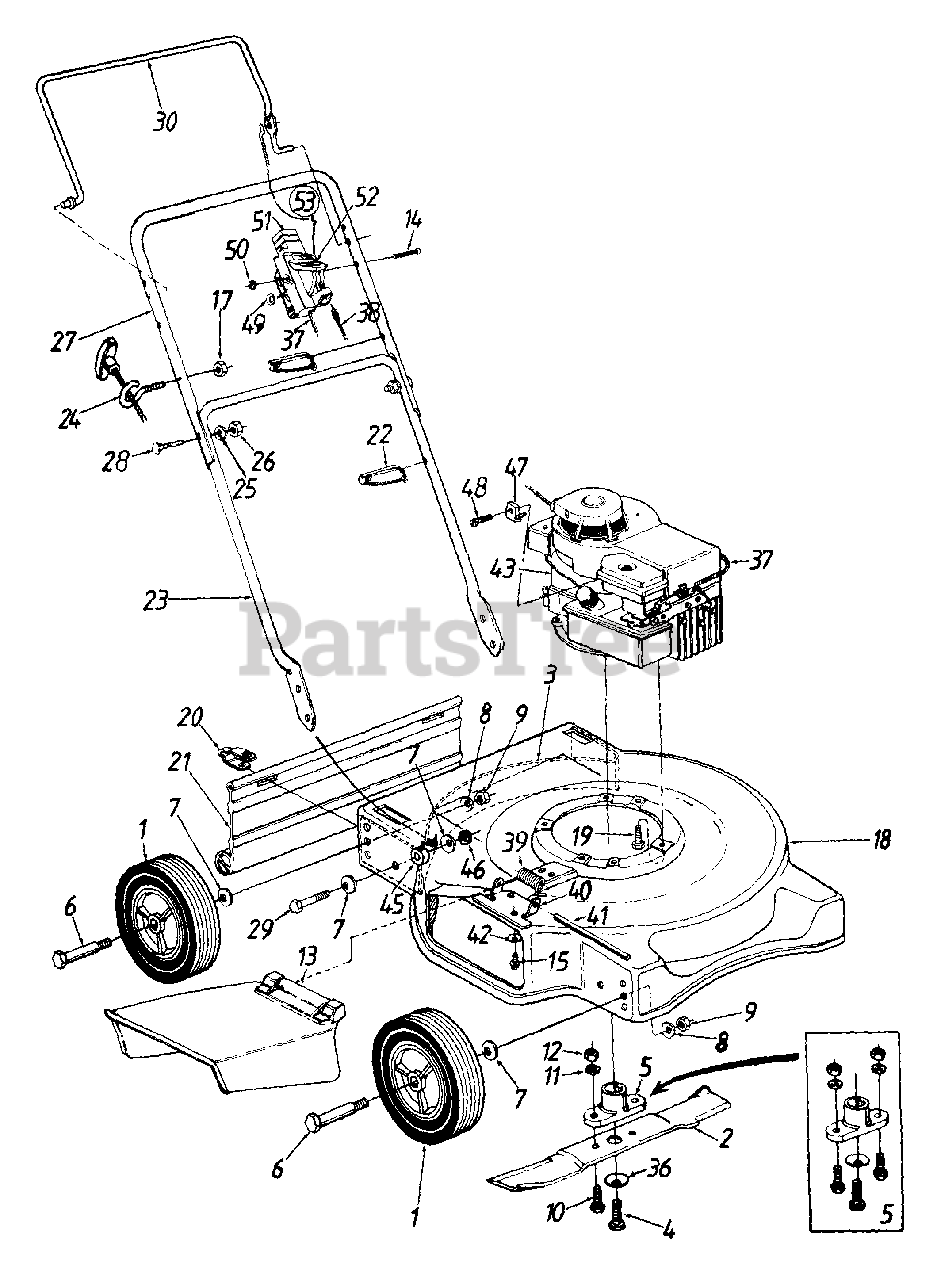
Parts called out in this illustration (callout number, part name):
1	Wheel Ass'y. Complete
2	20" Blade
5	Blade Adapter Kit (Keyed)
6	Axle Bolt
7	Bell-Wash..380" I.D. x .88"
8	Bell-Wash..39" I.D. x 1.13"
9	Hex Nut 3/8-16 Thd.
10	Hex Bolt 3/8-24 x 1" Lg.
11	L-Wash. 3/8" I.D.
12	Hex Nut 3/8-24 Thd.
13	Chute Deflector Ass'y.
14	Oval C-Sunk Scr.
15	Self-Tap Scr. 1/4-20 x .5" Lg.
17	Hex L-Nut 1/4-20 Thd.
20	Hinge Clip
21	Rear Flap 16.69" Lg.
22	Cable Tie
24	Rope Guide
25	L-Wash. 5/16" I.D.
26	Hex Nut 5/16-18 Thd.
29	Hex Bolt 3/8-24 x 1.5" Lg.
36	Bell-Wash..39" I.D.
37	Throttle Control Wire - 51" (B&S)
38	Control Cable - 36" (B&S)
39	Torsion Spring
40	Adapter Plate
41	Hinge Pin
42	Bell-Wash 1/4" I.D.
43	Engine
45	Spacer
46	Hex L-Nut 3/8-24 Thd
47	Casing Clamp (B&S)
48	Hex Wash. Hd. Scr. #10-32 x .62" Lg (B&S)
49	Spring Wash..66" I.D.
50	Hex L-Nut 1/4-20 Thd.
51	Throttle Body
52	Throttle Lever
53	Throttle Box Comp.
